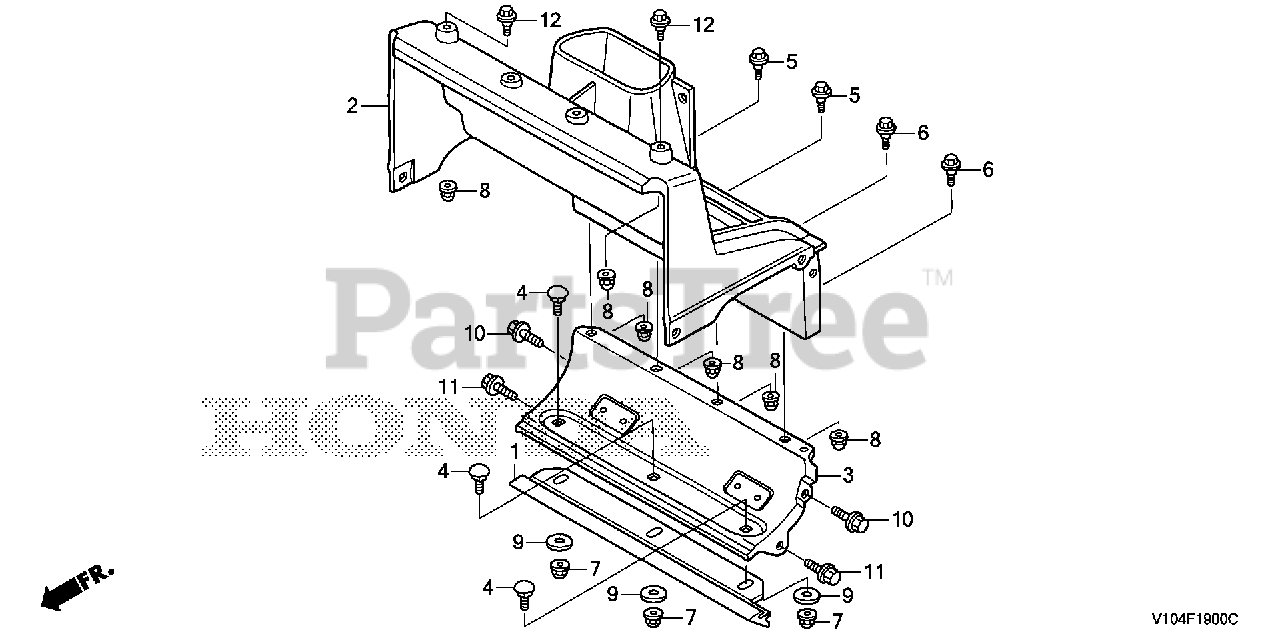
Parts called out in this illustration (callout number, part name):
1	BLADE, SCRAPER
2	HOUSING, AUGER
3	HOUSING, AUGER (LOWER)
4	BOLT, SPECIAL (8X20)
5	BOLT, TOP COVER
6	BOLT, CHUTE SETTING
7	NUT, FLANGE (8MM)
8	NUT, SELF-LOCK (6MM)
9	WASHER (8.5MM)
10	BOLT, FLANGE (8X16) Use from Engine SN 1000016.
11	BOLT, FLANGE (8X16)
12	BOLT, CHUTE SETTING
